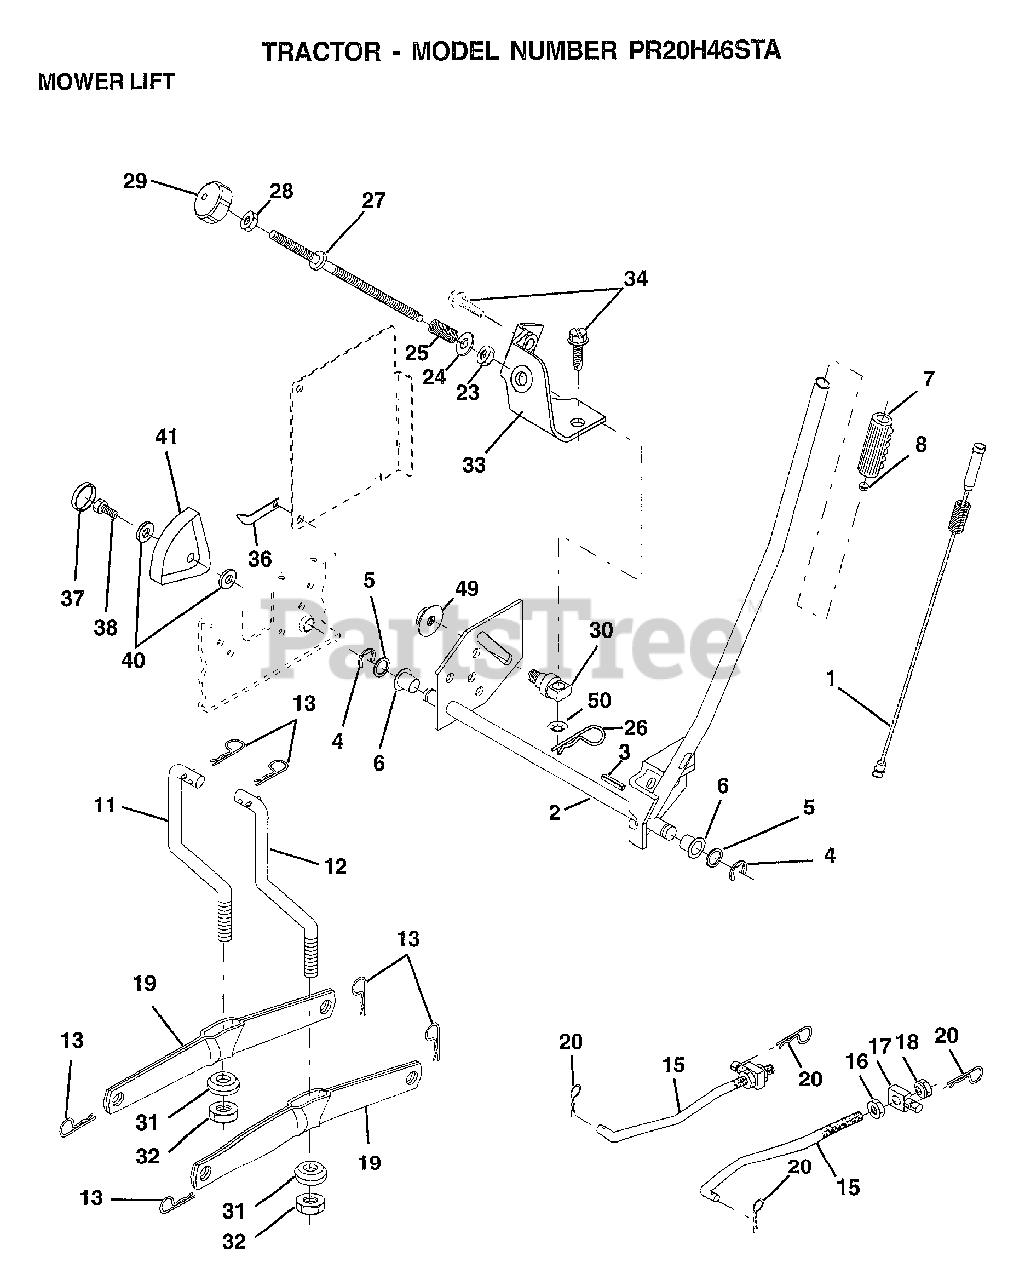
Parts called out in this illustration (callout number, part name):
1	WIRE ASM W.SPRING
2	"SHAFT ASM LIFT,RH"
3	PIN-GROOVE LT
5	WASHER
6	NYLON BEARING
7	GRIP HANDLE
8	BUTTON PLUNGER
15	LINK, FRONT
16	NUT
17	TRUNION
18	NUT.LK.W/WSH.1/2.
19	ARM SUSP REAR
20	RETAINER SPRING
23	NUT T
24	WASHER
25	SPRING T
26	RETAINER CLIP
28	NUT
29	KNOB INF 3/8-16
30	TRUNNION
31	BEARING PVT LH
32	NUT.CROWNLOCK.3/8
34	SCREW
36	POINTER-INDICAT
37	"PLUG,HOLE"
38	SCREW
40	WASHER
41	INDICATOR HEIGHT
49	NUT.HXFLG.LOCK.
50	NUT PUSH M
